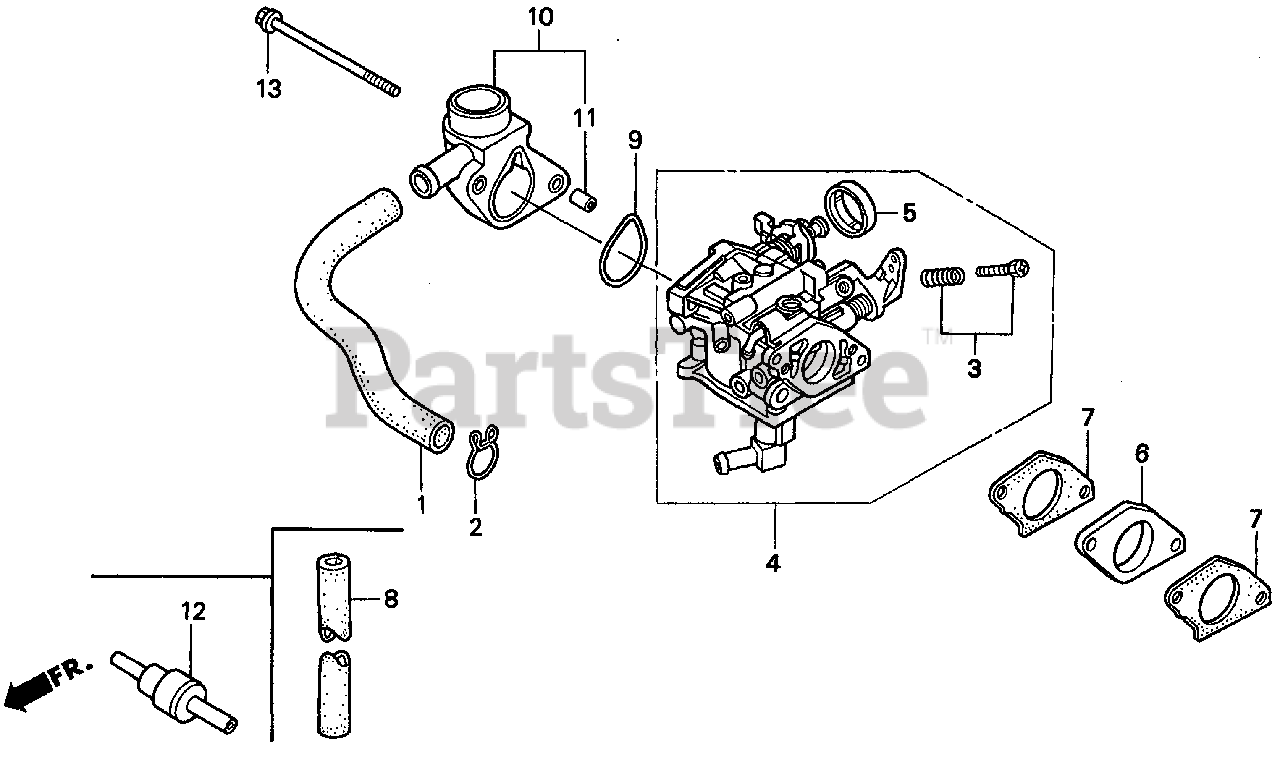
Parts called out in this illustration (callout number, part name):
1	TUBE, BREATHER
2	CLIP, BREATHER TUBE
3	SCREW SET
4	CARBURETOR ASSY. (BGL0A A)
5	CAP, CHOKE LEVER DUST
6	INSULATOR, CARBURETOR
7	GASKET, CARBURETOR
8	RUBBER, SUPPORTER
9	GASKET, AIR CLEANER
10	ELBOW, AIR CLEANER
11	COLLAR, DISTANCE
12	VALVE, DASHPOT CHECK
13	BOLT, FLANGE (6X105)
